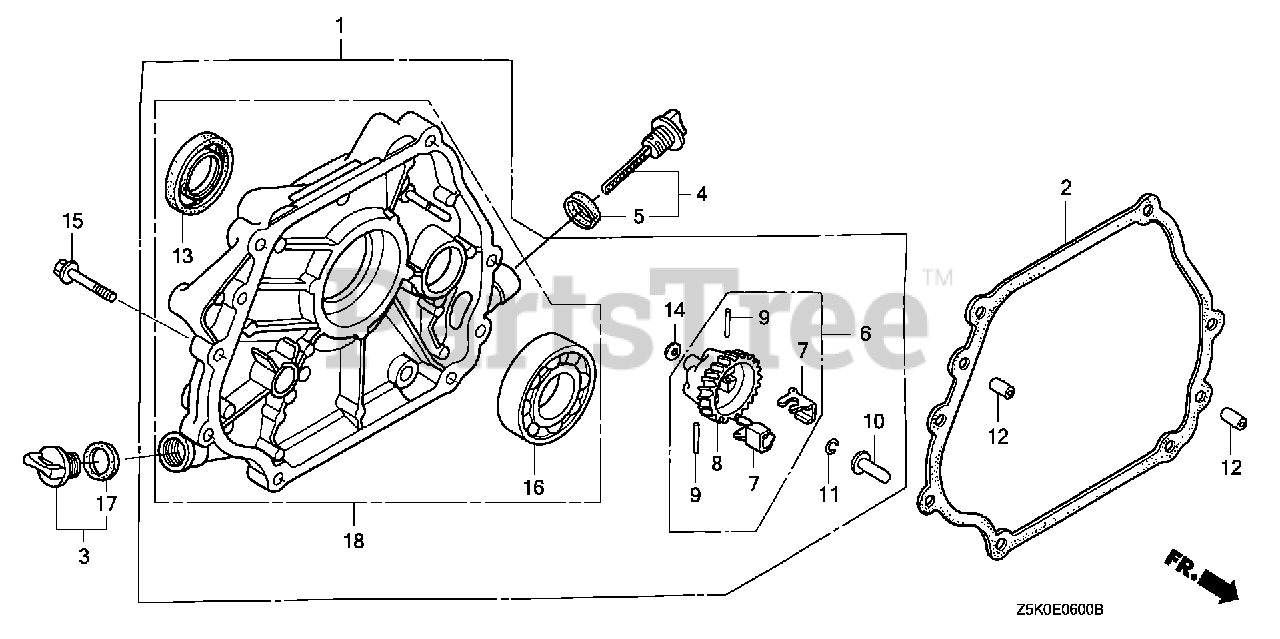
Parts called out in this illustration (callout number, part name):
1	COVER ASSY., CRANKCASE
2	GASKET, CASE COVER
3	CAP ASSY., OIL FILLER (BLACK)
4	CAP ASSY., OIL FILLER
5	GASKET, OIL FILLER CAP
6	GOVERNOR ASSY.
7	WEIGHT, GOVERNOR
8	HOLDER, GOVERNOR WEIGHT
9	PIN, GOVERNOR WEIGHT
10	SLIDER, GOVERNOR
11	CLIP, GOVERNOR HOLDER
12	PIN, DOWEL (8X12)
13	OIL SEAL (30X46X8) (NOK ASIA)
14	WASHER, PLAIN (6MM)
15	BOLT, FLANGE (8X35)
16	BEARING, RADIAL BALL (6206)
17	GASKET, OIL FILLER CAP
